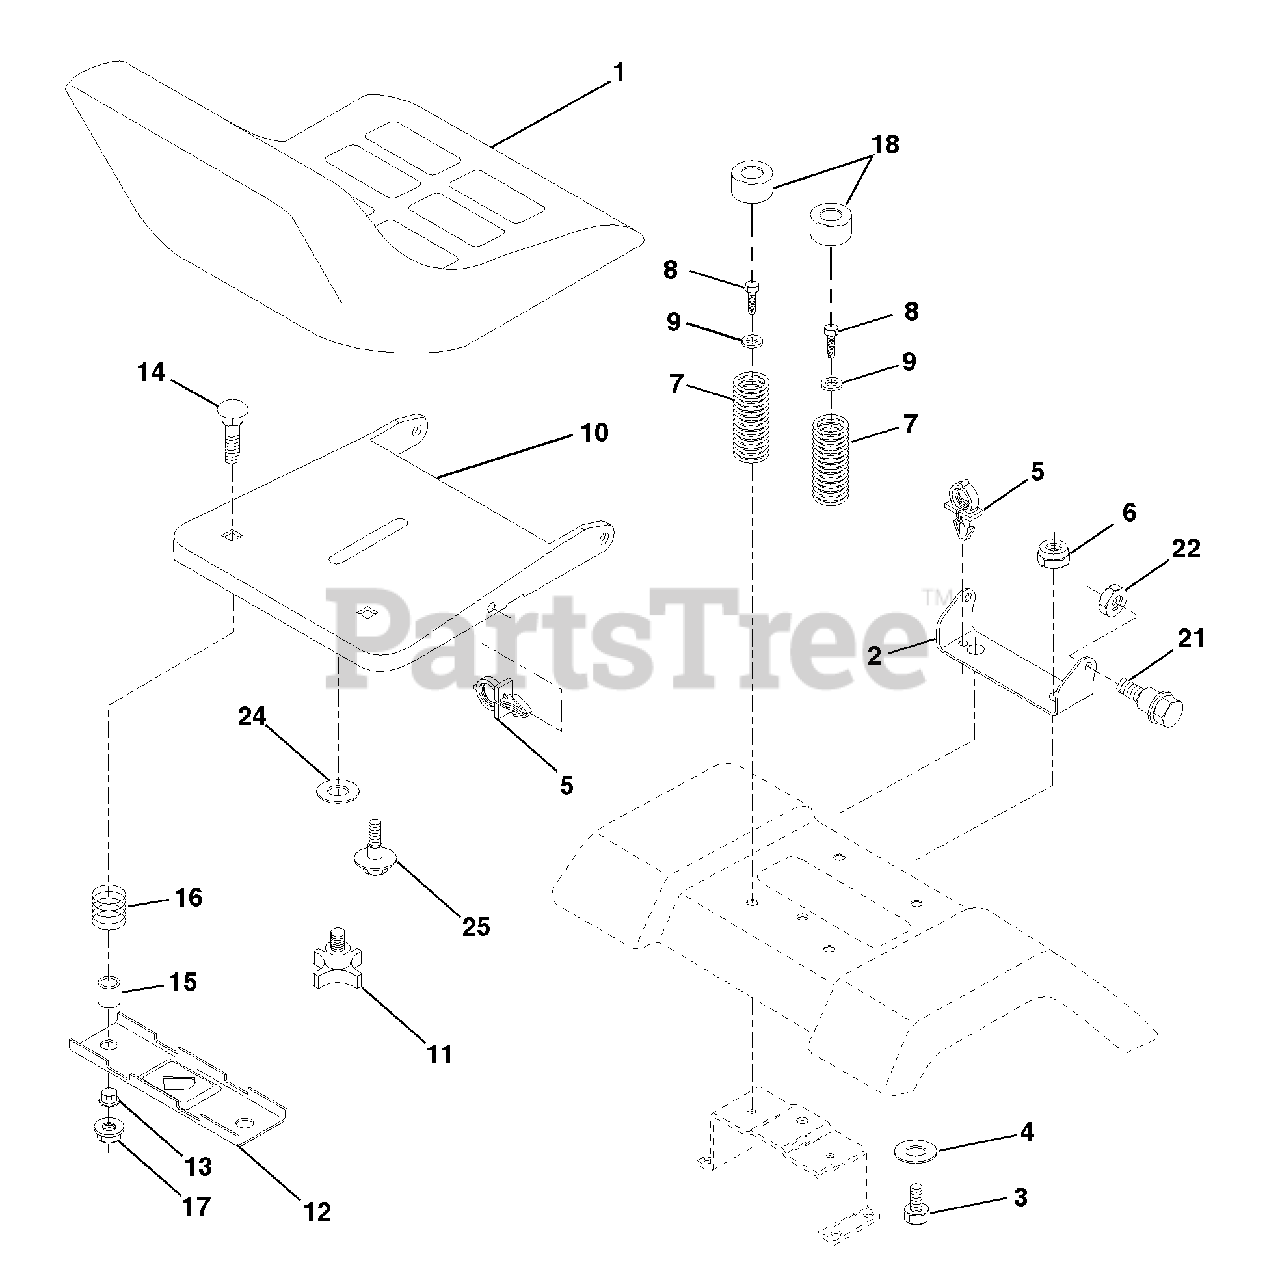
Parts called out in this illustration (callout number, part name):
1	Seat
2	Bracket Pivot Seat 8.720
3	Bolt Fin Hex 3/8-16unc X 1
4	Washer 13/32 X 1 X 10 Ga
5	Clip Push-In
6	Nut Hex w/Ins. 3/8-16 Unc
7	Spring Seat Cprsn 2.250 Blk Zi
8	Screw Thdrol 3/8-16 X 1 Ty-tt
9	Washer 13/32 X 1 X 14 Ga.
10	Pan Seat
11	Knob Seat 1/2-13 Unc
12	Bracket Mounting Switch
13	Bushing Snap Blk Nyl 50 Id
14	Bolt Rdhd Sqnk 1/4-20 x 1-1/2
15	Spacer Split 28 x .88 Zinc
16	Spring Cprsn Plate
17	Nut Lock 1/4 Lge Flg Gr 5 Zinc
18	Cap Spring Seat
21	Bolt Shoulder 5/16-18 Unc
22	Nut Hex Lock W/Ins 5/16-18
24	Washer 17/32 X 1-3/16 X 12 Ga.
25	Bolt Shoulder 5/16-18 X 62
